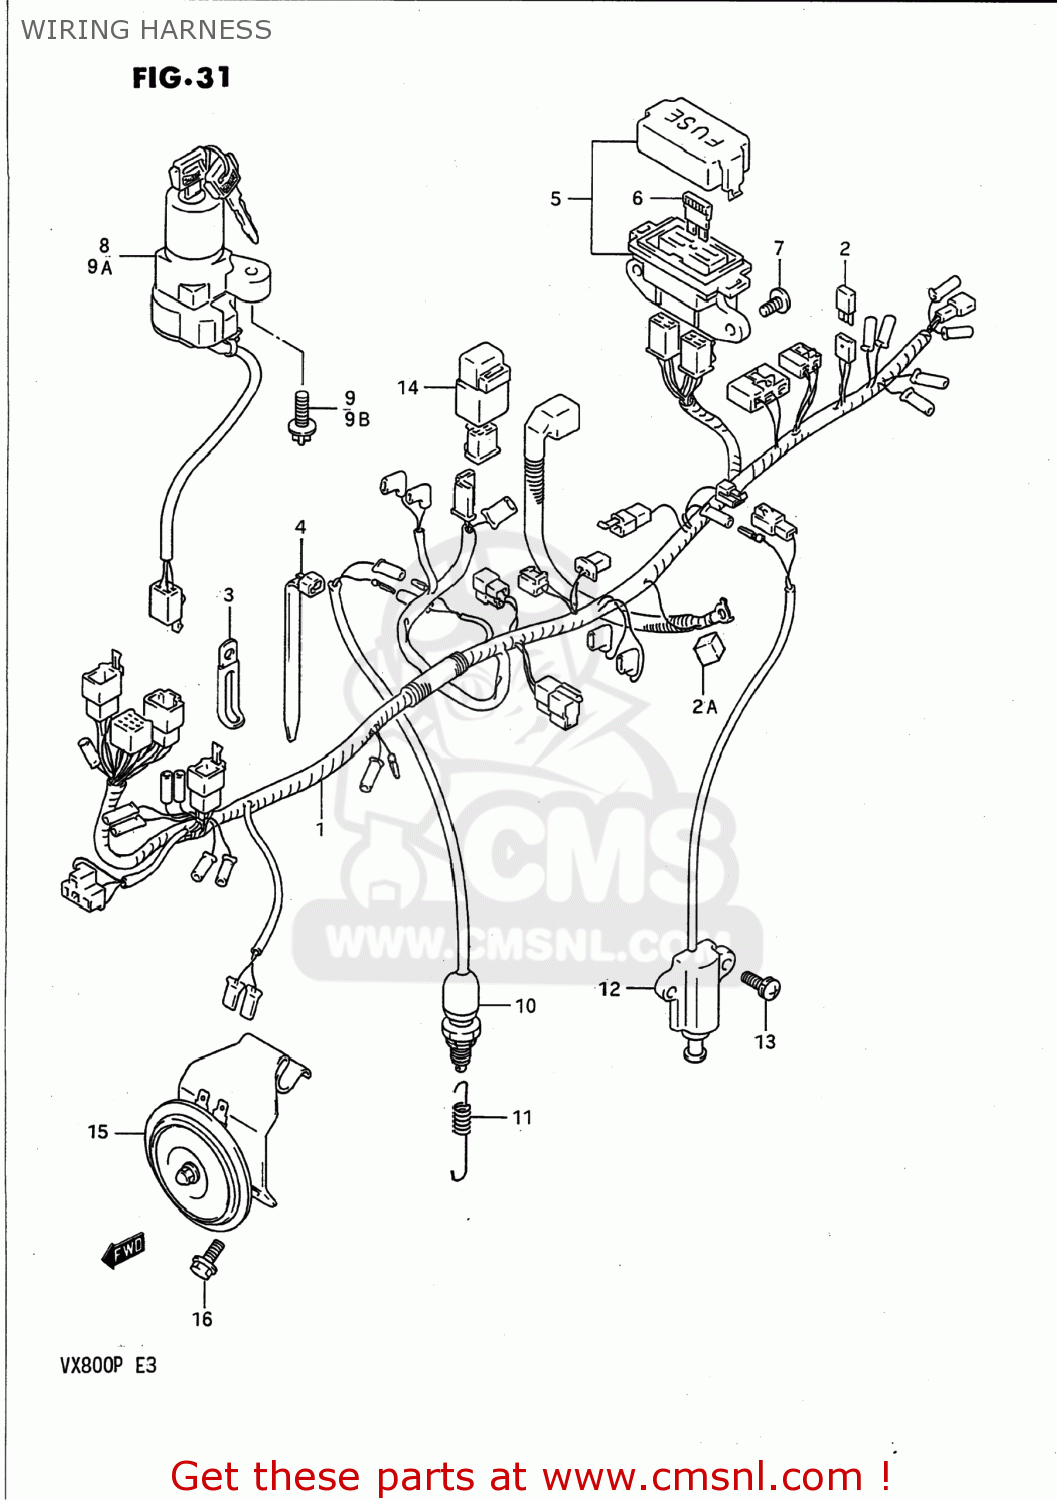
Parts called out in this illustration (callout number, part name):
1	HARNESS,WIRING
2	DIODE(STANLEY DE8804)
2A	CAP,BATTERY PLUS
3	CLAMP
4	CLAMP(L:100)
5	BOX ASSEMBLY,FUSE
6	FUSE(10A)
7	SCREW
8	LOCK ASSEMBLY,STEERING
9	SCREW(6X18)
9A	LOCK ASSEMBLY,STEERING
9B	SCREW(6X18)
10	SWITCH ASSY,STOP LAMP
11	SPRING
12	SWITCH ASSEMBLY,SIDE STAND
13	VIS
14	RELAY ASSEMBLY
15	HORN ASSEMBLY
16	BOLT
17	KEY,BLANK
